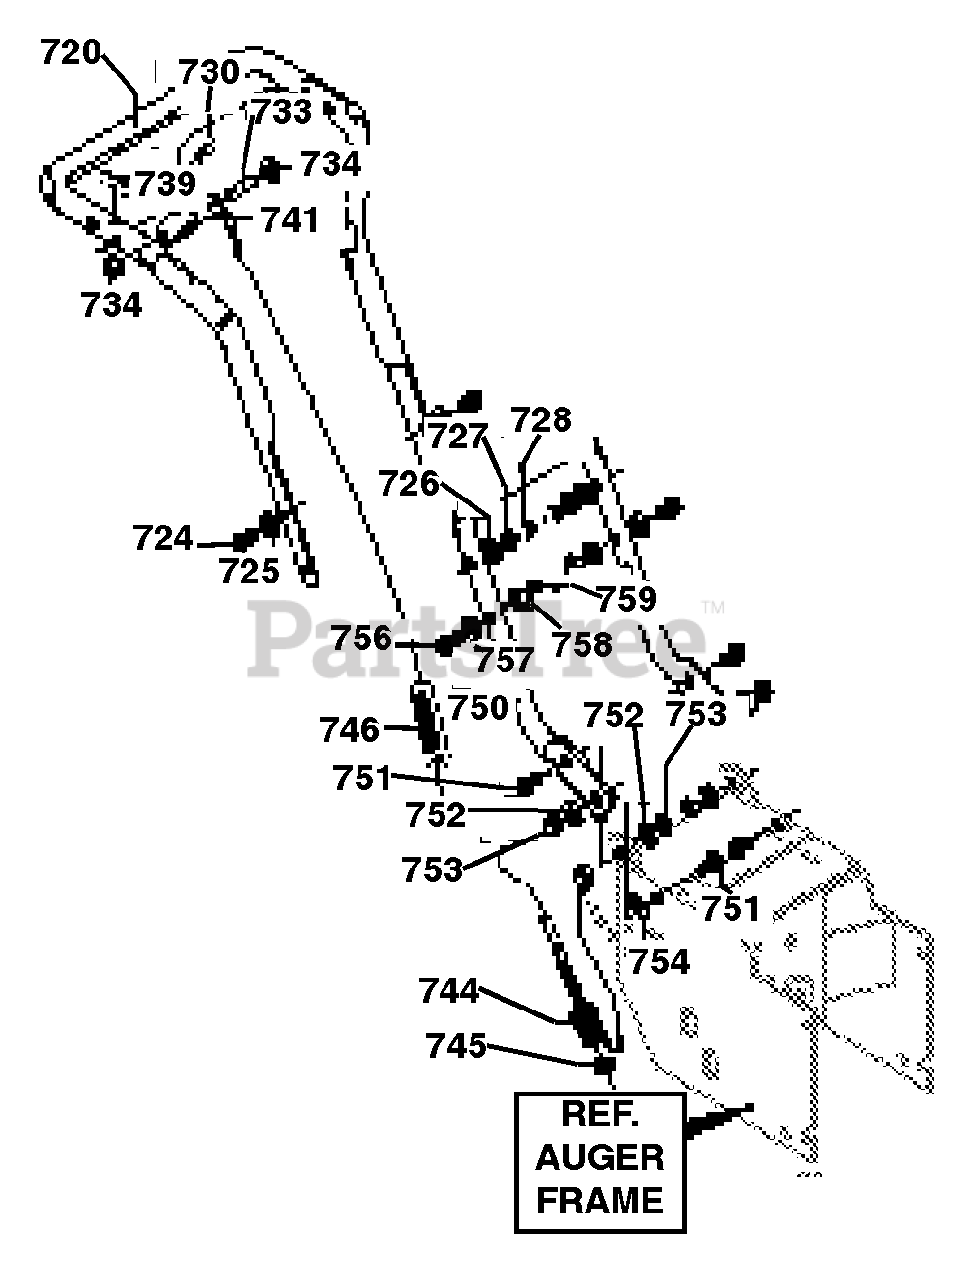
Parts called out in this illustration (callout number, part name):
720	Handle, Upper
724	Screw, 5/16-18 x 2.75
725	Flatwasher, 344 x .69 x .065
726	Washer, .328 x .60 x .09
727	Nut, 5/16-18
728	Stop, Red Plastic
730	Kit for Handle, Assy RH
733	Pin, Clutch
734	Nut, Push on Cap
739	Bumper, Rect
741	Cable, Clutch
744	Spring, Auger Clutch
745	Nut, 1/4-20 Reghexctrlk
746	Boot, Clutch Spring
750	Handle, Lower
751	Screw, 5/16-18 x 1.00
752	Washer, 328 x .60 x .09
753	Nut, 5/16-18 Reghex
756	Screw, 5/16-18 x 2.00
757	Flatwasher, .344 x .69 x .065
758	Washer, .328 x .60 x .09
759	Nut, 5/16-18 RegheX
